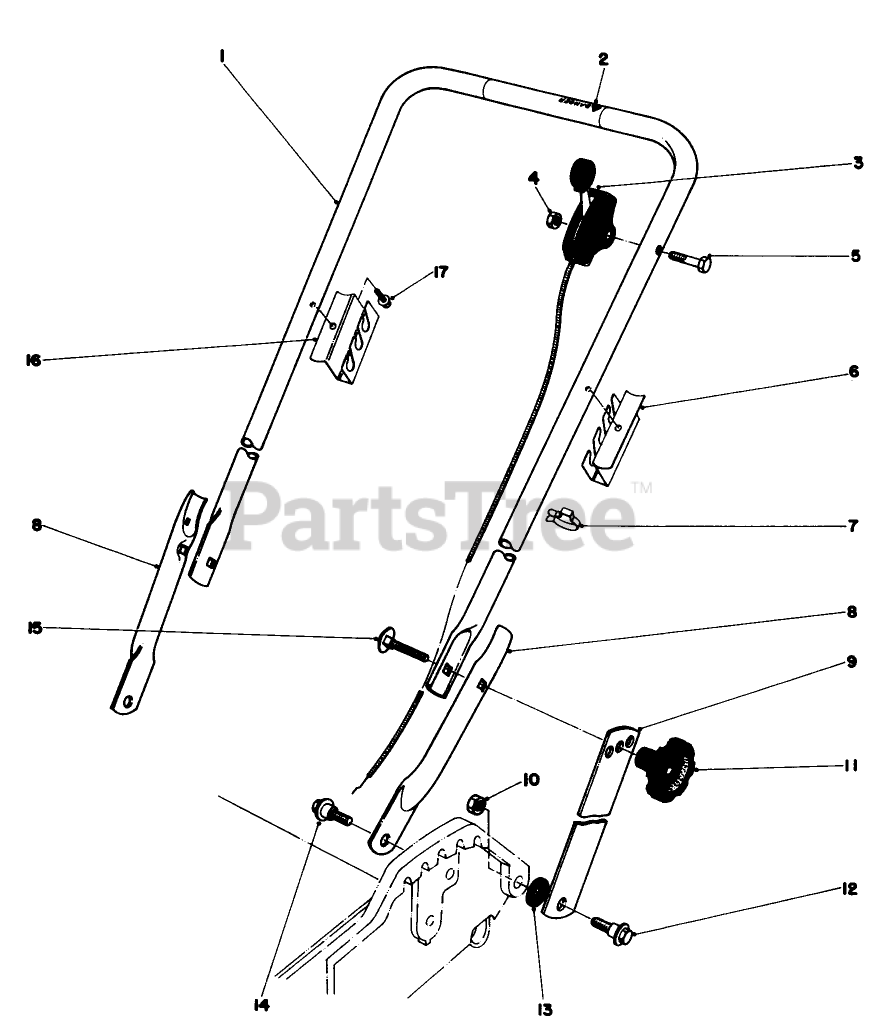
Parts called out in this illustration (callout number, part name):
5	SCREW-HH
6	SUPPORT BAG LH
7	BOWDEN CLIP
12	SCREW-SHOULDER
13	SPACER
14	SCREW-SHOULDER
15	SCREW-HANDLE
17	SCREW-HWHTF
